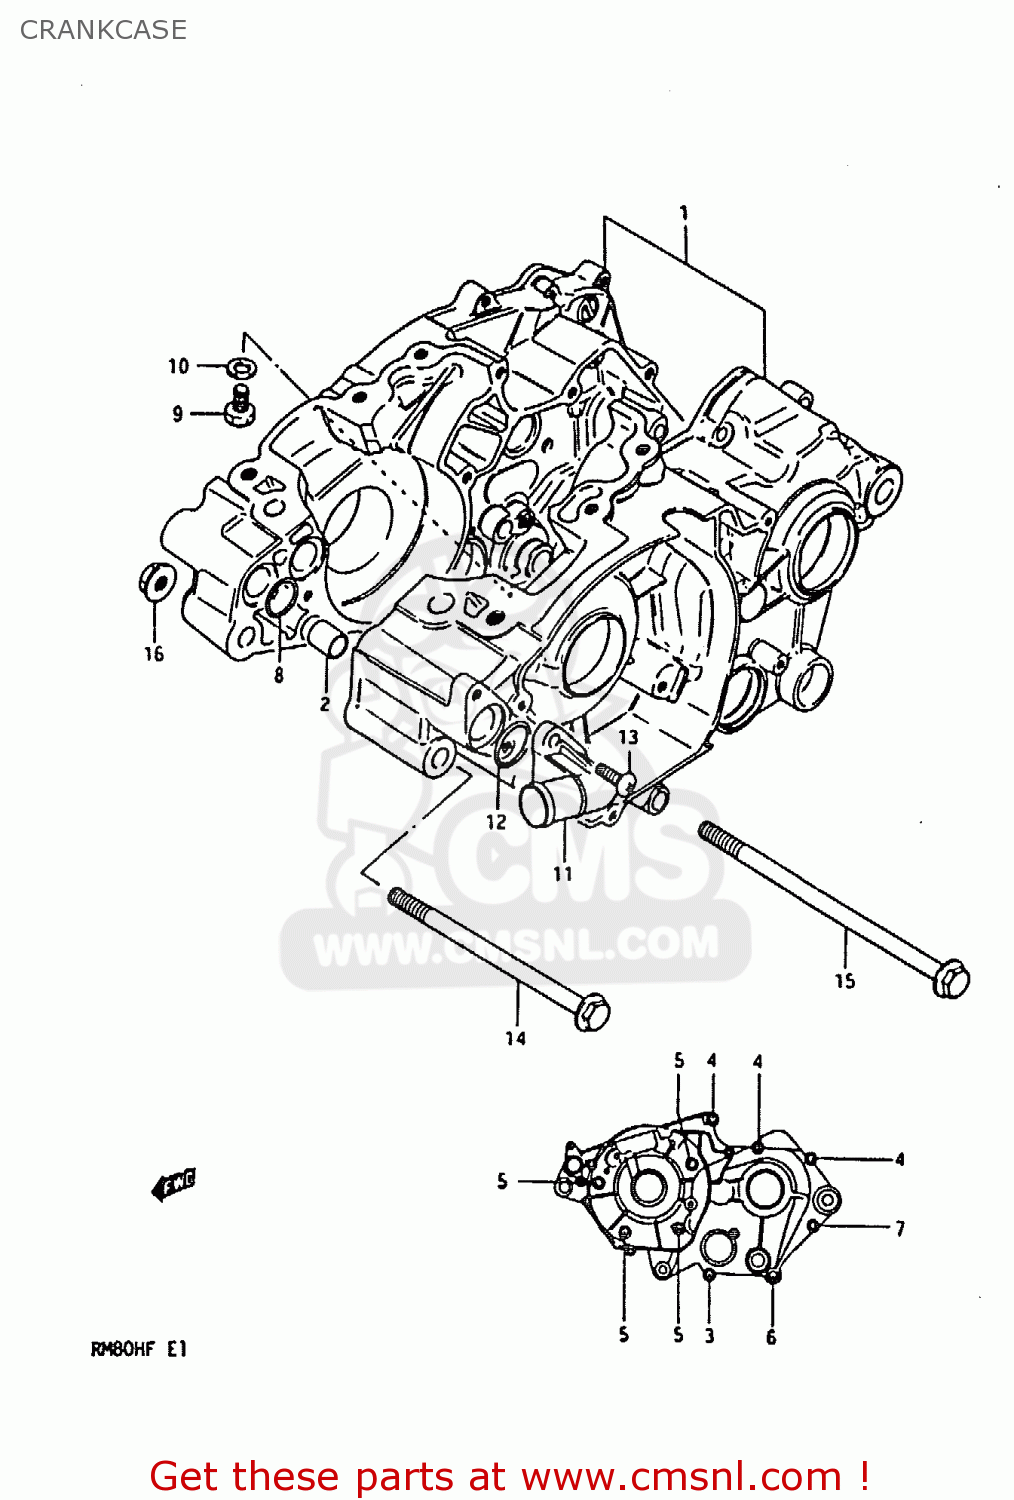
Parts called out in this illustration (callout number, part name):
1	CRANKCASE SET
2	PIN
3	SCREW
4	SCREW (6X35)
5	SCREW
6	SCREW (6X45)
7	SCREW
8	O-RING,BOSS
9	BOLT
10	GASKET 8.2X14X1 (NAS)
11	CONNECTOR,WATER HOSE
12	O-RING,BOSS
13	SCREW
14	BOLT(8X95)
15	BOLT(8X125)
16	NUT
